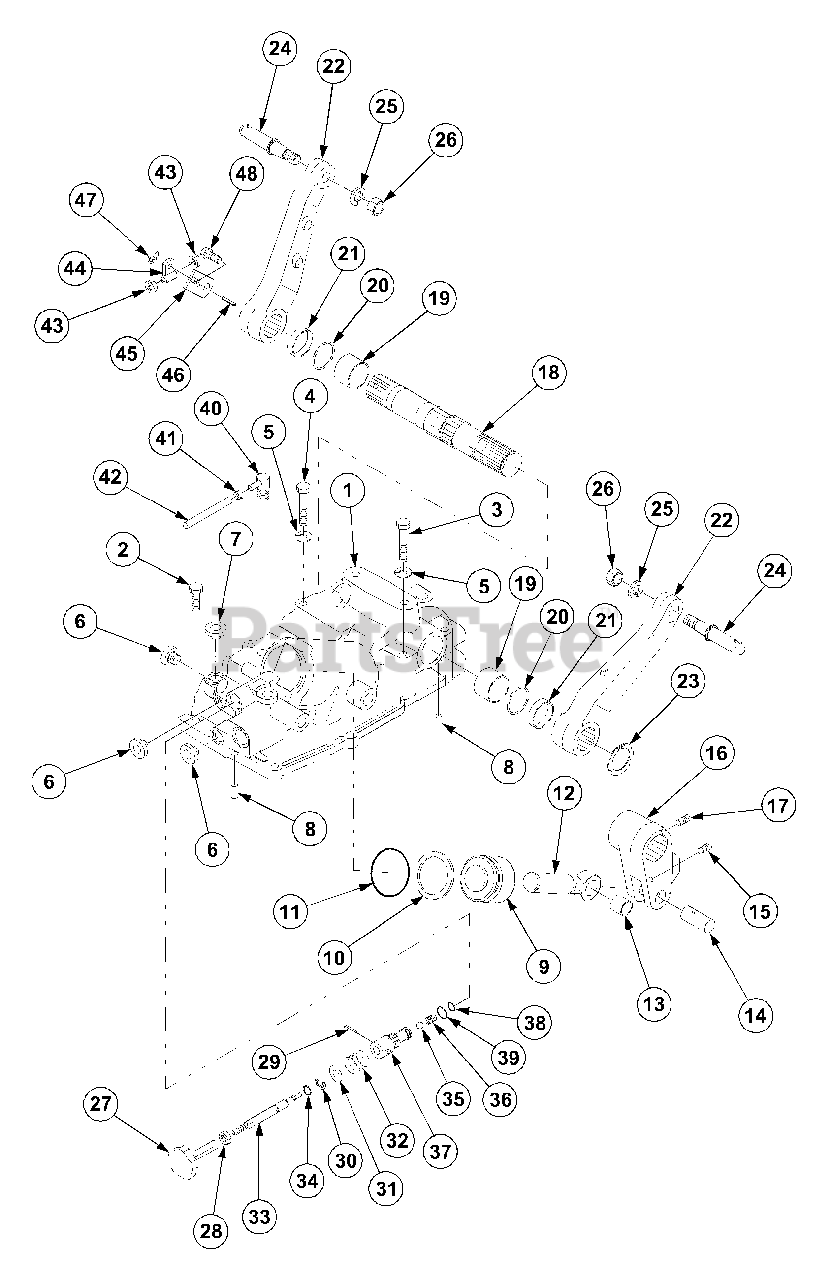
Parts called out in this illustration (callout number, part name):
1	Housing,Hydraul
2	Bolt,w/Washer
5	Washer,Spring
18	Shaft,Hydraulic
25	Washer,Spring
30	E-Ring
48	Bolt,w/Washer
